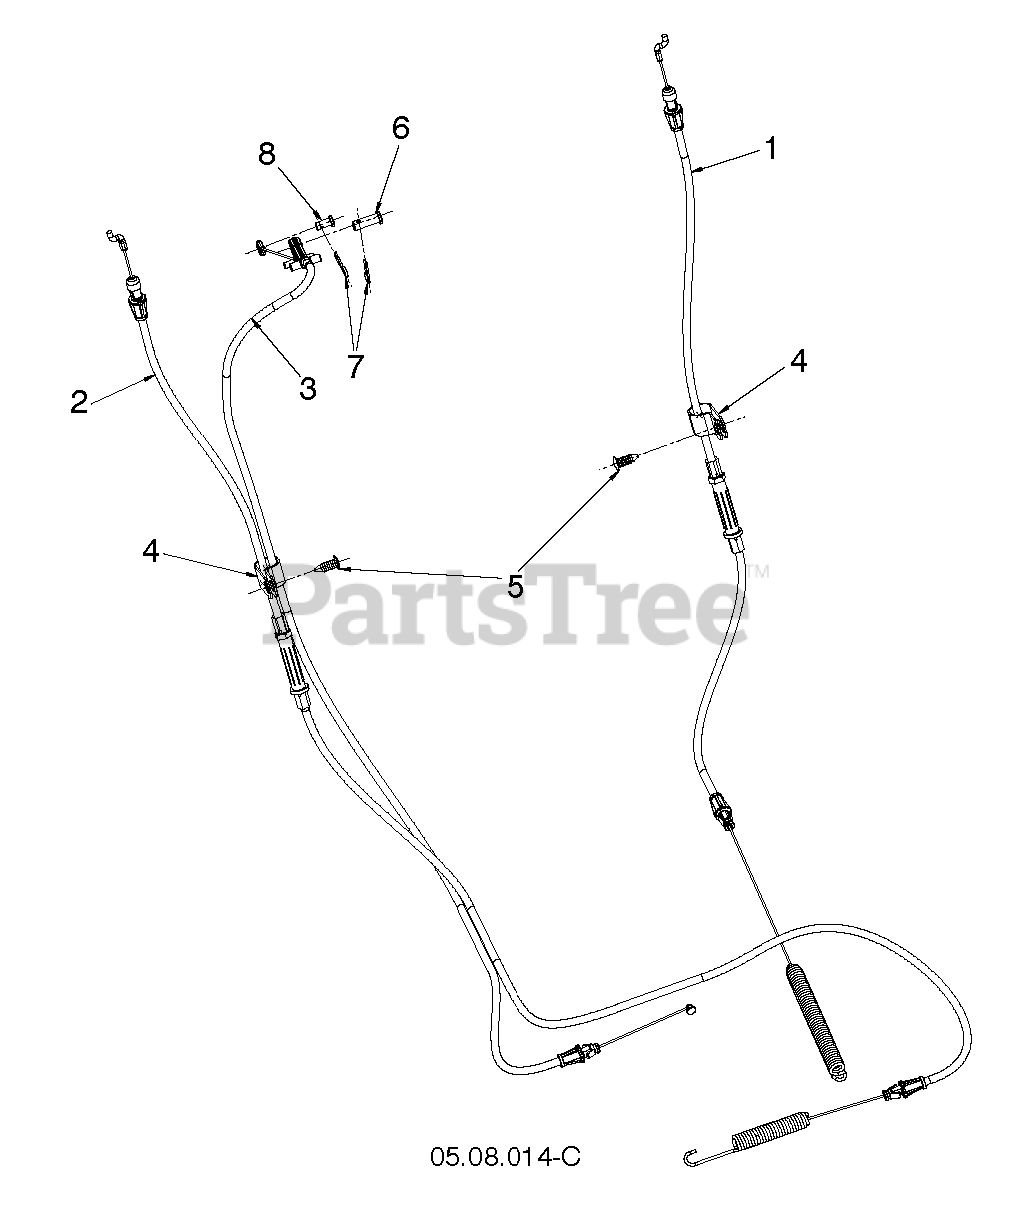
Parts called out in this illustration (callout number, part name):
1	CABLE.DRIVE CONTROL W/ADJ
2	CABLE.CONTROL.AUGER
4	CLIP.CABLE.BLK
5	FASTENER.PUSH.O.250X0.783
6	PIN CLEVIS 5/16X.875
7	HAIRPIN.SOFT.ZINC.059X1.125
8	PIN CLEVIS .25 X .31
